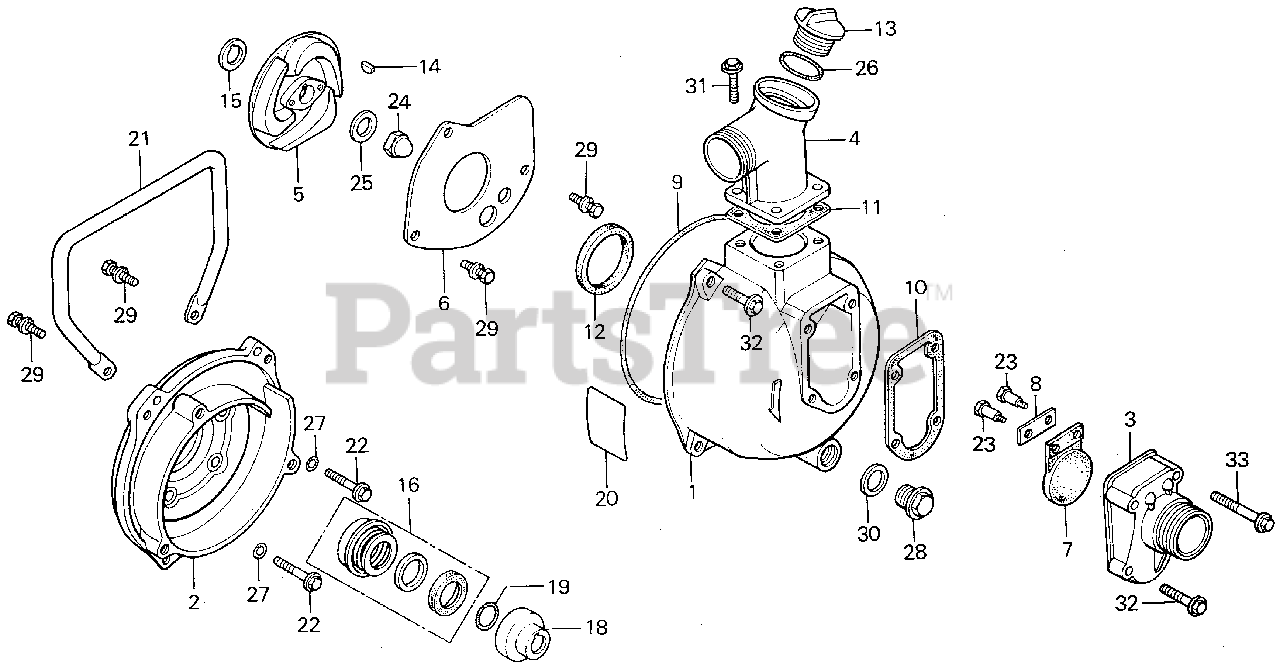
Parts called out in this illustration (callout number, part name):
2	COVER, CASE *NH2M* (METALLIC SILVER)
3	PIPE PUMP, IN.
4	PIPE, PUMP OUTLET (NOT AVAILABLE)
6	DISK, FRICTION
7	VALVE, IN.
8	RETAINER, VALVE
9	RING, CASING SEAL
10	GASKET, IN.
11	GASKET, OUTLET
12	RING, CENTER SEAL
13	CAP, FILLER
14	KEY, IMPELLER
15	SHIM, ADJUSTER
16	SEAL ASSY., MECHANICAL WATER
18	COLLAR, SEAL SETTING
19	O-RING, MECHANICAL SEAL
20	PLATE, DESCRIPTION
22	BOLT, PUMP SETTING
23	BOLT, CHOKE LEVER
24	NUT, IMPELLER
25	WASHER (13MM)
26	O-RING, FILLER CAP
27	O-RING (7.5MM)
28	BOLT, DRAIN PLUG (20MM)
29	BOLT-WASHER (8X20)
30	WASHER, DRAIN PLUG (20MM)
31	BOLT, FLANGE (8X25)
32	BOLT, FLANGE (8X35)
33	BOLT, FLANGE (8X50)
